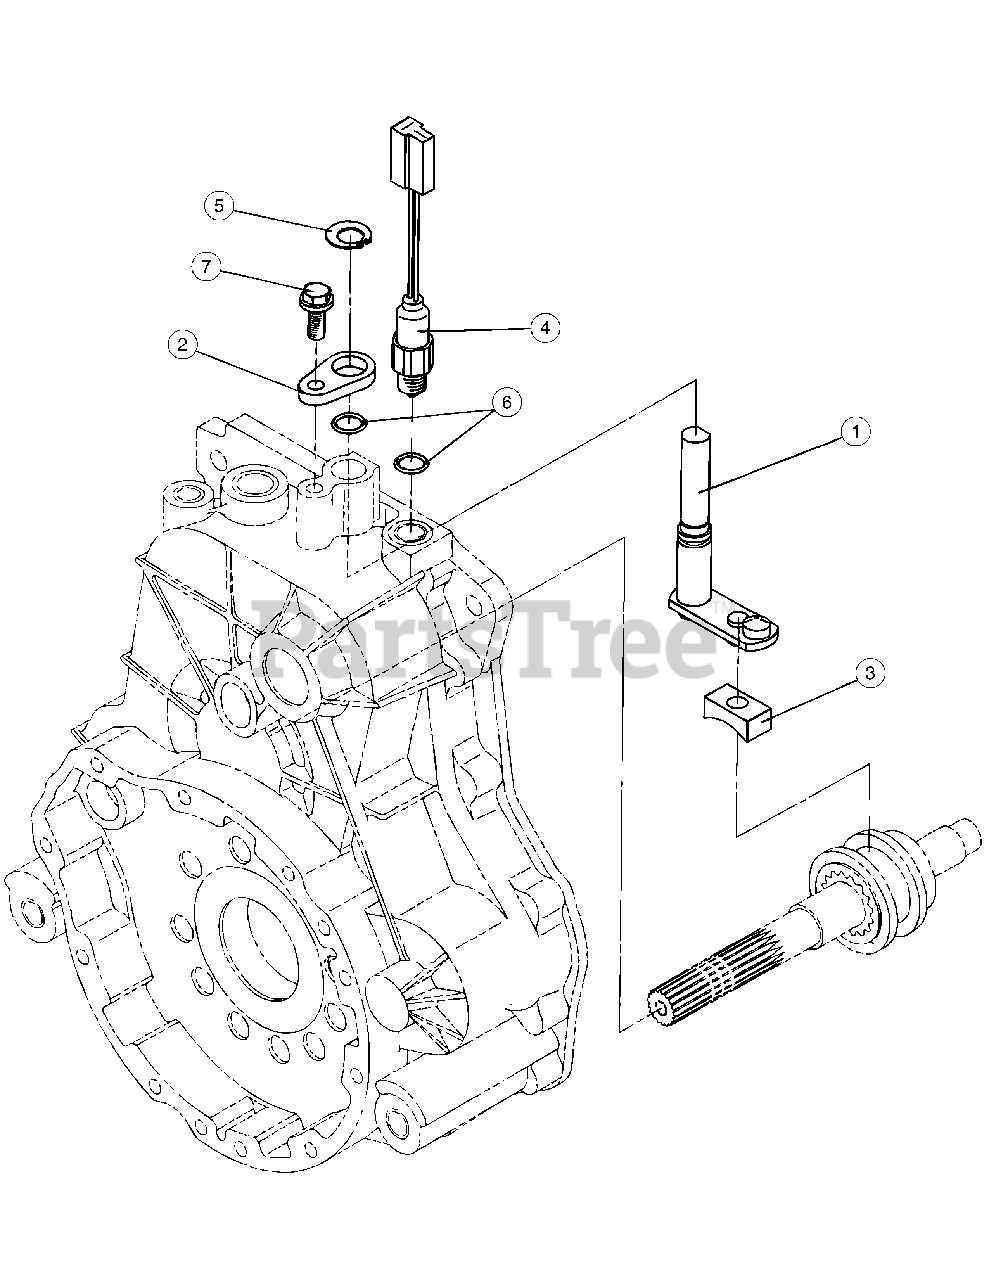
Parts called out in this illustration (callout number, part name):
2	Plate
5	Ring, 14
6	Packing, P 12.5
7	Tapping Screw, 8 x 20
